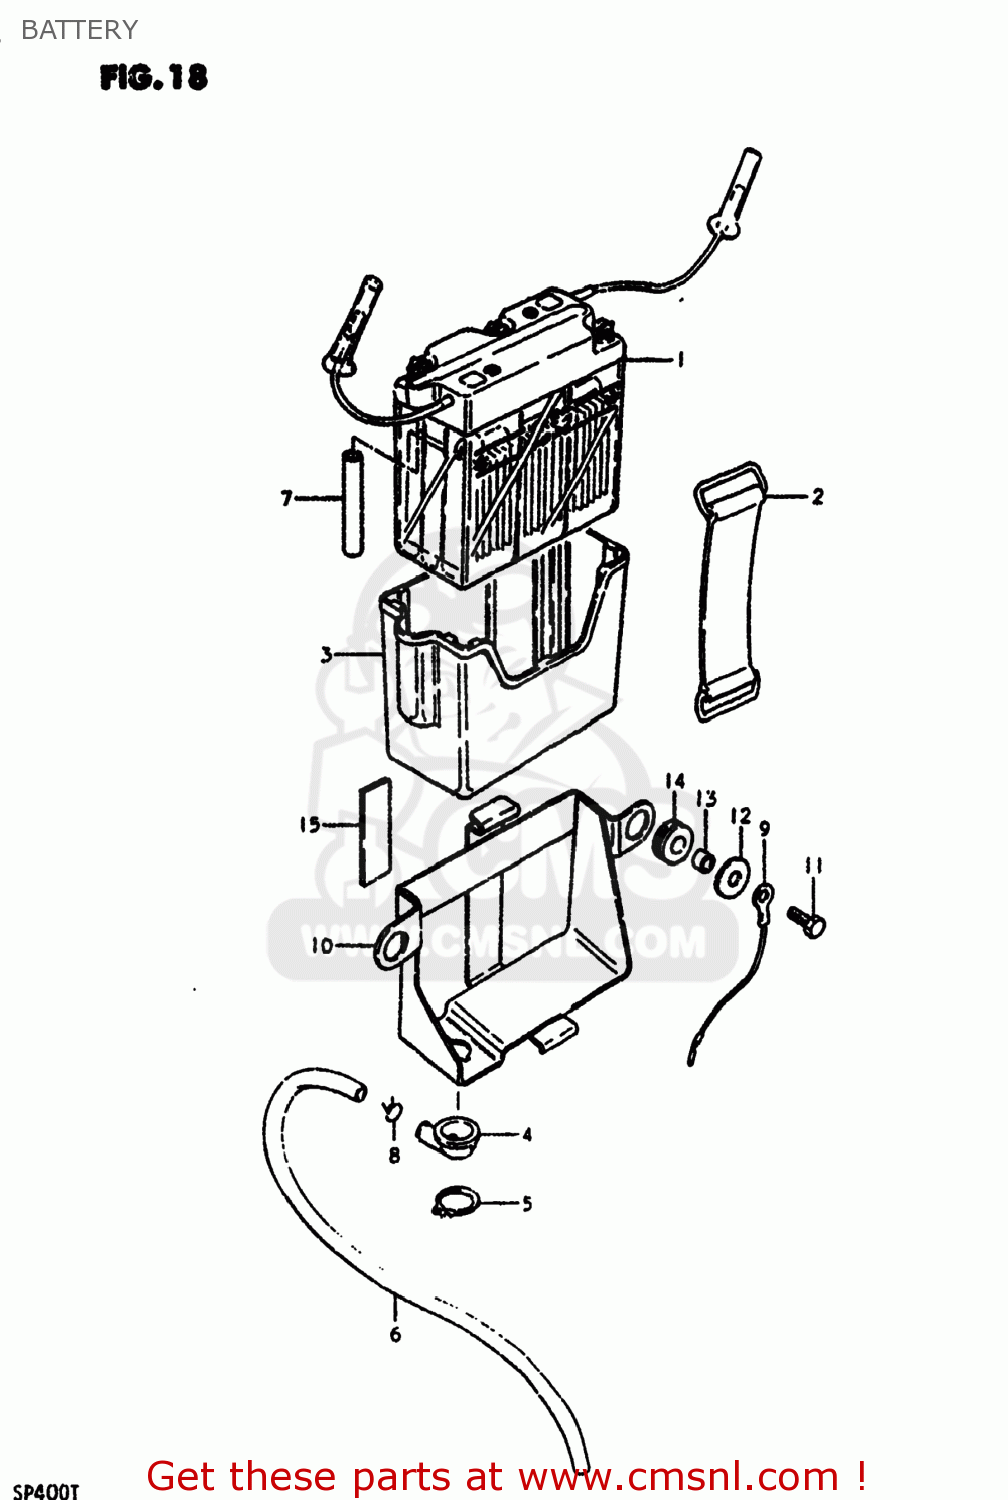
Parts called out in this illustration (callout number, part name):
1	BATTERY ASSEMBLY
2	BAND
3	CASE,BATTERY
4	FUNNEL,BATTERY EXHAUST
5	CIRCLIP
6	HOSE,BATTERY EXHAUST
7	HOSE, EXHAUST (L:45)
8	CLIP
9	LEAD WIRE
10	HOLDER,BATTERY
11	BOLT
12	WASHER (6.5X20X1.2)
13	SPACER (7X9X7)
15	PROTECTOR,20X9
